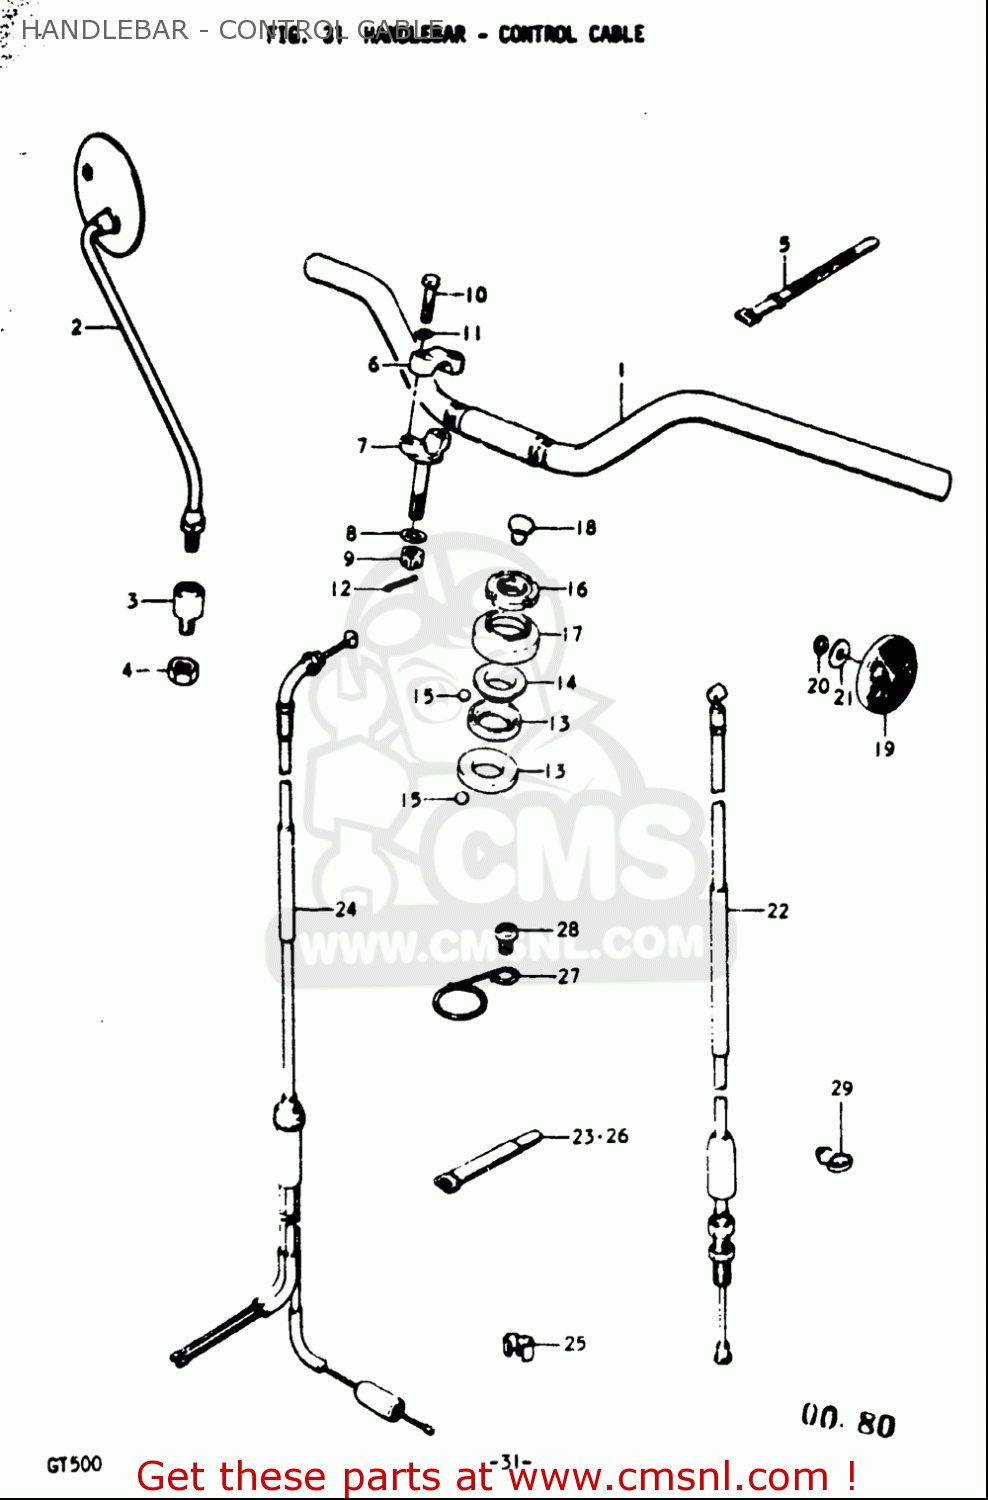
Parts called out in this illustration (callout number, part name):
1	HANDLEBAR
2	MIRROR ASSEMBLY,LEFT
4	NUT
5	CLAMP(L:120)
6	HOLDER,HANDLEBAR
8	WASHER(10.5X28X2.3)
9	NUT
10	BOLT
11	WASHER,LOCK
12	COTTER PIN
13	LACE,STEERING INNER LWR
14	LACE,STEERING OUTER UPR
15	BALL
16	NUT,STEERING STEM(25X44X10)
17	DUST SEAL,STEERING UPR
18	CAP(OD:20)
